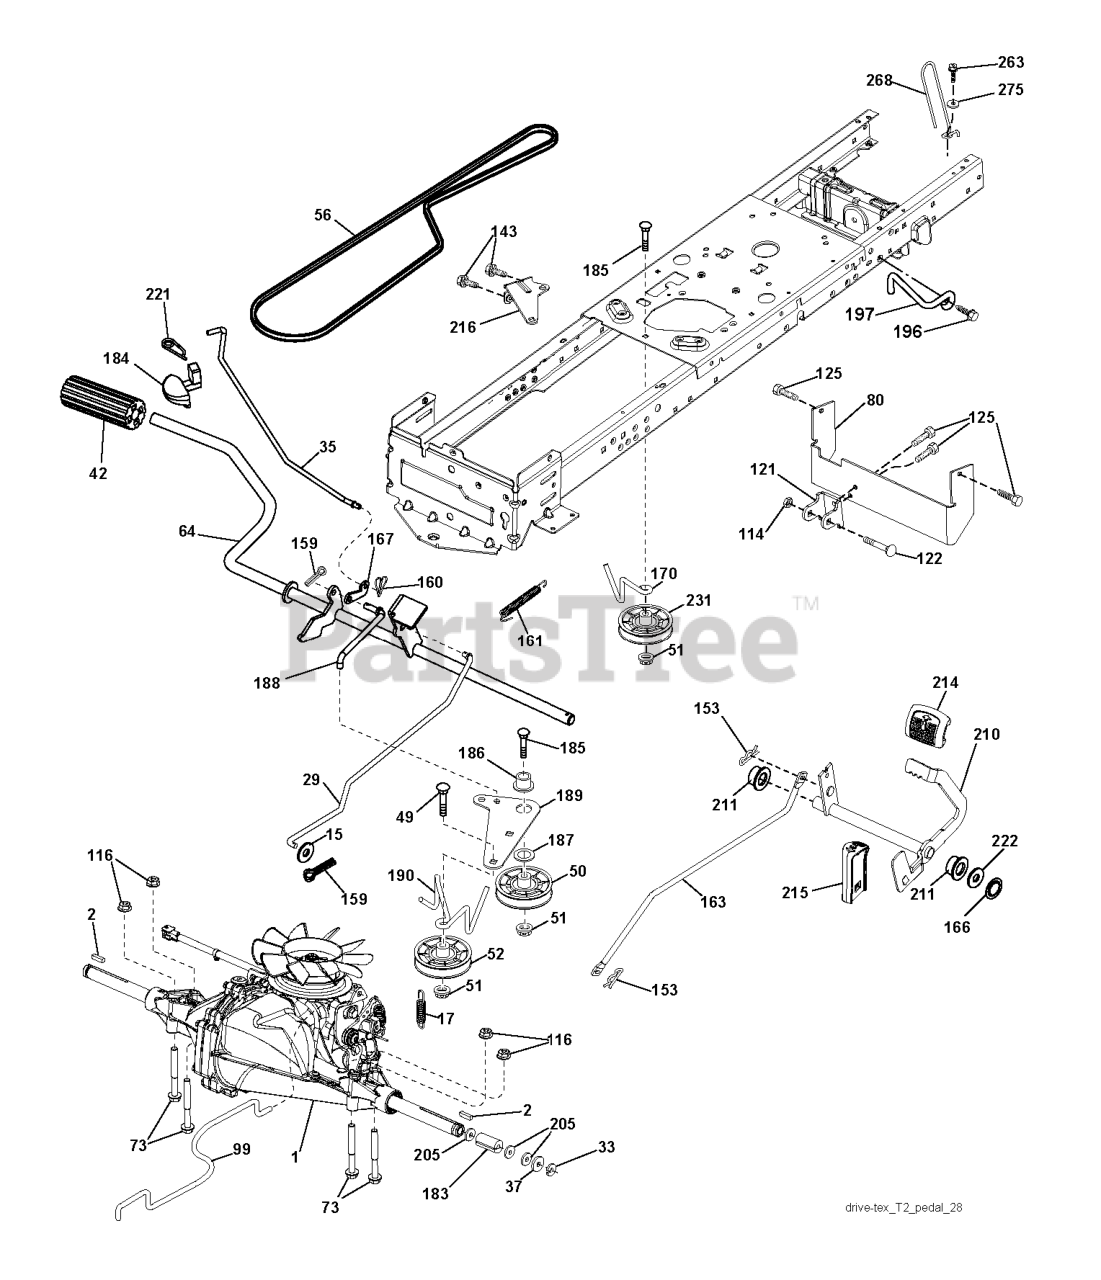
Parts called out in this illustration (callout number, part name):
2	SQUARE KEY
15	WASHER
17	SPRING.BRAKE.HG3000/3500
29	ROD.BRAKE.T2.TEX
35	ROD.CNTRL.PARK.PREDATOR.LT.TEX
42	PEDAL COVER T
50	IDLER.FLAT.910.OFFSET
51	NUT LOCK FLG 3/8-16 UNC
52	IDLER.V-GROOVE.910.OFFSET
64	SHAFT.ASM.PEDAL.BRK.CNTR
73	BOLT HEX 5/16-18 GR 5
80	RP.STRAP.TORQUE.FS.T2
99	ROD.ASM.BYPASS.SPRING.T2.FS
114	NUT.71038.31-18.HEX.NYLOCK
116	NUT LOCK HEX FLANGE 5/16-18
121	BRACKET STRAP TORQUE
122	BOLT.5/16-18X2.5
125	SCREW
143	Screw 5/16-18 x 1/2 Hex, Self Tapping 5/16-18 x 1/2
153	RETAINER M
159	COTTER PIN
160	RETAINER CLIP
161	SPRING, RETURN LT
163	ROD.CONTROL.PCH.T2.TEX
166	NUT.PUSH.625
167	LATCH.BRAKE.SPRING
170	KEEPER.CENTER SPAN.1.688
183	SPACER, AXLE PVST
184	HANDLE PARKING BRAKE
186	SPACER.RETAINER
187	WASHER 12/32X2X10GA
188	RP.LINK.CLUTCH.GROUND.DRIVE
189	BELLCRANK.GROUND.DRIVE.TEX.
190	KEEPER.BELLCRANK.DRIVE
196	SCREW 3/8-16X1
197	LINK.CLUTCH.ANIT-ROTAT
210	ROCKER.ASM.PEDAL.CONTR
211	BEARING.NYLON
214	PEDAL.FORWARD.PAD.TEX
215	PEDAL.REVERSE.TEX.GT.4
216	BRACKET.PULLEY.IDLER.W/TEX
221	RETAINER.SPRING.CLIP.H
222	WASHER 21/32 X 1-1/4 X 10 GA.
231	IDLER.V-GROOVE.1.688.OFFSET
263	SCREW, 3/8-16X3/4
268	WASHER
275	GUARD MUFFLER
